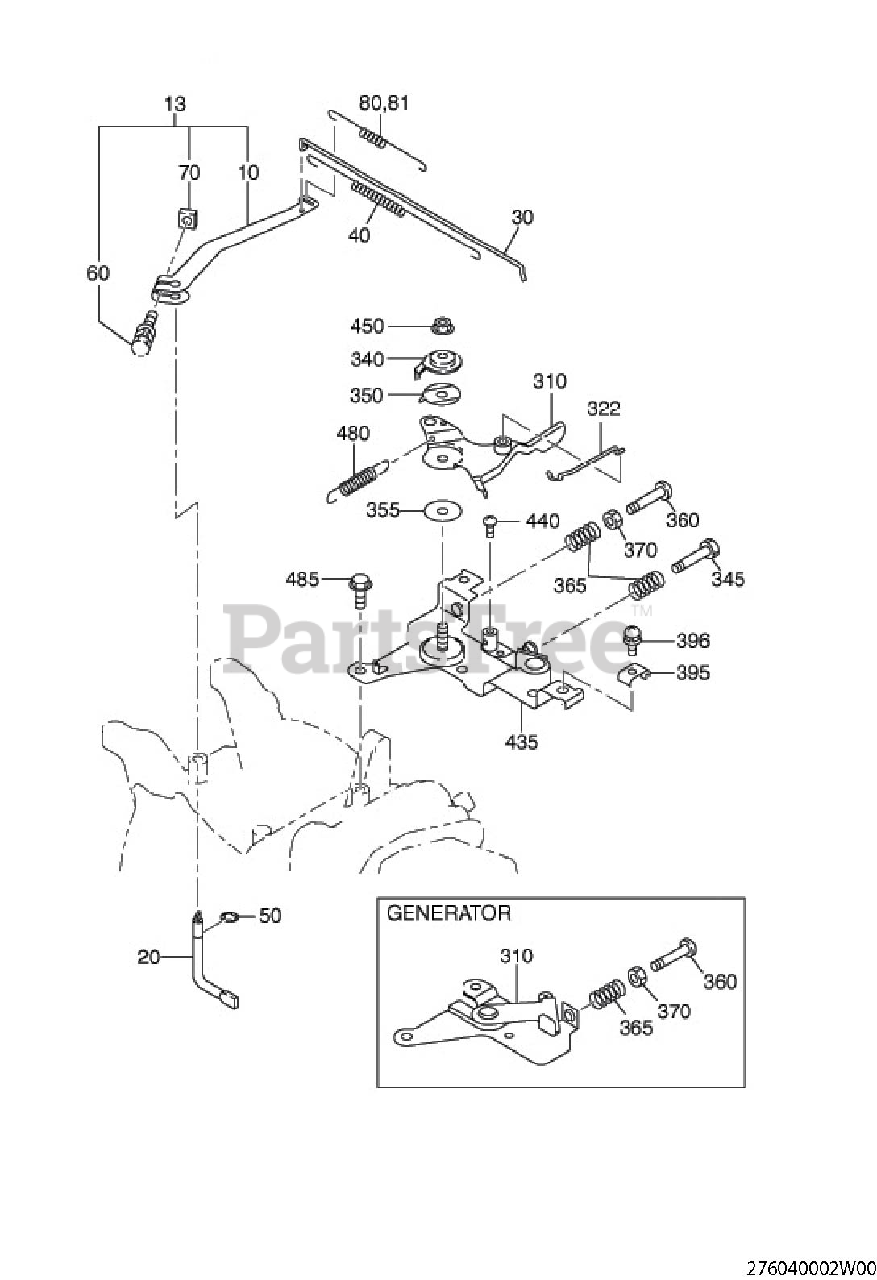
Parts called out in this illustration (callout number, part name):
10	GOVERNOR LEVER
20	GOVERNOR SHAFT
30	GOVERNOR ROD CP
40	ROD SPRING
60	BOLT AND WASHER AY
70	NUT
80	GOVERNOR SPRING
310	SPEED CONT. LEVER CP
350	WASHER
355	FRICTION WASHER
360	SCREW
365	SPRING (ADJUST)
396	SCREW AND WASHER AY
435	SPEED CONT.BRKT CP
440	SCREW
450	SELF LOCK NUT
480	RETURN SPRING
485	FLANGE BOLT
